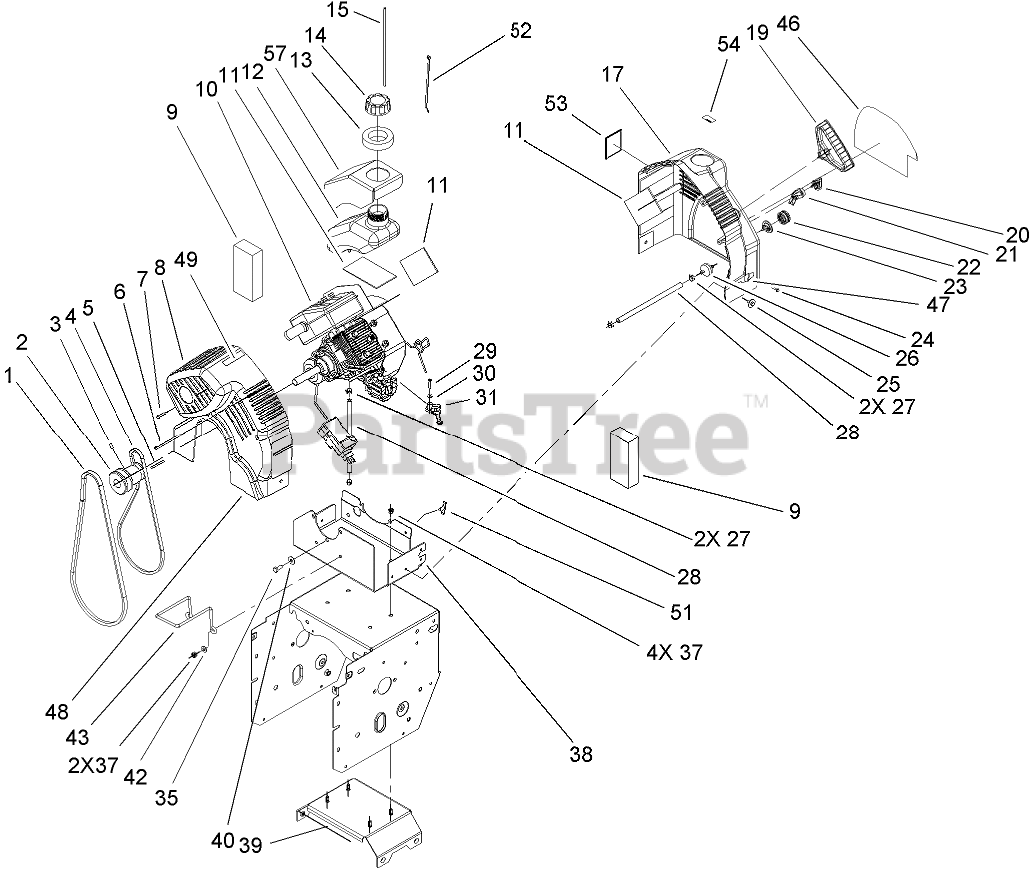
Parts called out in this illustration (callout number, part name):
1	V BELT-AUGER
2	PULLEY-ENGINE
3	SCREW-SET, HSH
4	V BELT-TRACTION
5	KEY-SQUARE
7	SCREW-HWH
8	COVER-FRONT, STYLING
11	PAD-FOAM
12	TANK-FUEL
13	SEAL-FOAM
14	GAS CAP ASM
15	HOSE-PRIMER
17	COVER ASM
19	HANDLE-ROPE START
20	KEY-IGNITION
21	SWITCH
22	BULB-PRIMER
23	BODY-PRIMER
24	SCREW-PLASTITE
25	SCREW-WASHER HEAD
26	FILTER-FUEL
27	CLAMP-HOSE
28	LINE-FUEL
29	SCREW-PPH, PLASTITE
30	WASHER-FLAT
31	LEVER-CHOKE
35	SCREW-HH
37	NUT-LOCK, NI
38	PLATE-MOUNTING, ENGINE
39	FRAME BRACE ASM
40	WASHER-BELLEVILLE
42	WASHER-PLAIN
43	GUIDE-BELT
46	DECAL-PANEL
47	DECAL-STARTER, ELECTRIC
48	DECAL-CHOKE
49	DECAL-WARNING
51	CLIP-HARNESS
52	TIE-CABLE
54	DECAL-FUEL, 2 CYCLE
57	FOAM-TANK, FUEL
99	CORD-ELECTRIC
